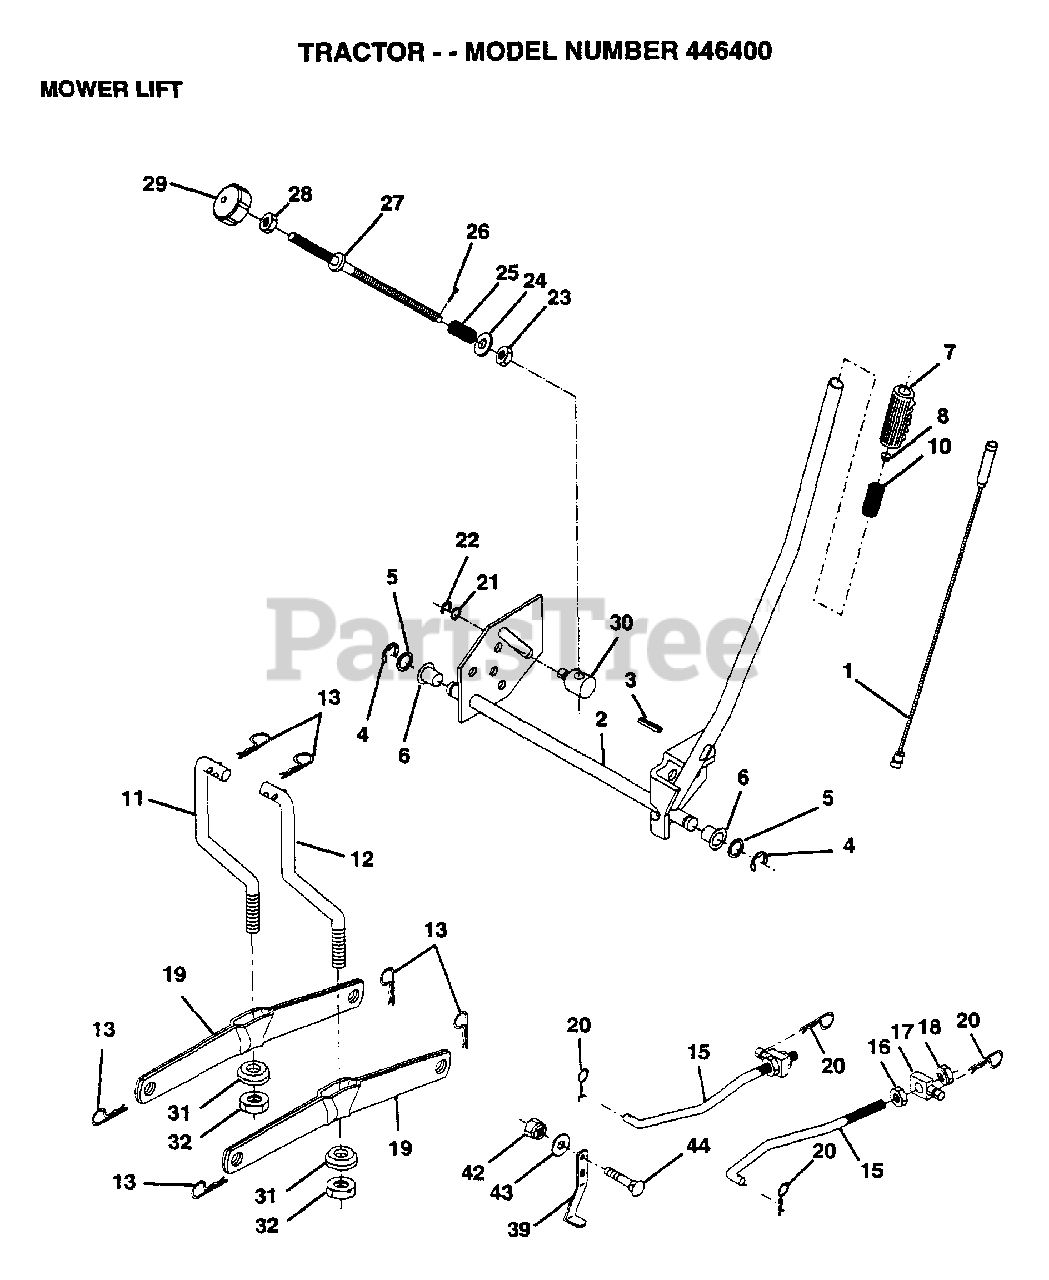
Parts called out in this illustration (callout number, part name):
1	WIRE.ASM.INNER
2	SHAFT.ASM.LIFT.RH
3	PIN GROOVE
5	WASHER
6	NYLON BEARING
7	GRIP
15	LINK.FRONT
16	NUT
17	TRUNION
18	NUT.LK.W/WSH.1/2.
19	ARM SUSP REAR
20	RETAINER.SPRING
21	WASHER
22	KLIP RING
23	NUT T
24	WASHER
25	SPRING.COMP.INF.H
27	ROD.ADJ.LIFT
28	NUT
29	KNOB INF 3/8-16
30	TRUNION LT
31	BEARING PVT LH
32	NUT.CROWNLOCK.3/8
39	STOP.OVER.CENTER
42	NUT
43	WASHER GT
44	BOLT
